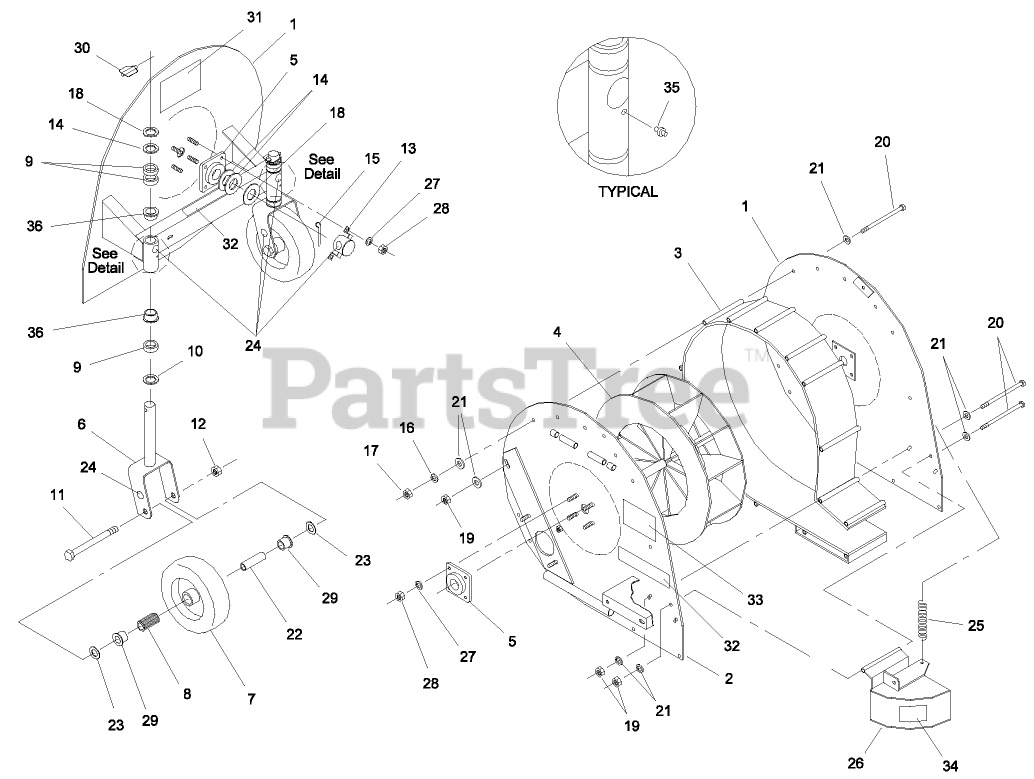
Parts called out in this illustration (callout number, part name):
1	BLOWER FRONT WA
2	BLOWER SIDE BACK WA
3	FAN RING WA
4	FN BLOWER WA
5	BEARING VF4S120
6	Caster Fork
7	Wheel-Castor (Incl. Ref. #8,37)
8	BEARING
9	SPACER
10	WASHER-THRUST
11	SCREW-HH
12	NUT-HF
13	FAN SHAFT GUARD WA
15	PIN-COTTER
16	WASHER-LOCK
17	NUT-HEX
19	NUT-LOCK, NI
20	Bolt
21	WASHER-FLAT
22	SPANNER
23	WASHER-FLAT
24	DECAL-GREASE
25	Spring
26	DEFLECTOR WA R
27	WASHER-LOCK
28	NUT-HH
29	BEARING-OUTSIDE
30	PIN-LYNCH
31	DECAL
32	DECAL - BLOWER 2670
33	DECAL
34	DECAL - AIR DEFLECTOR
35	ZERK
36	BUSHING
